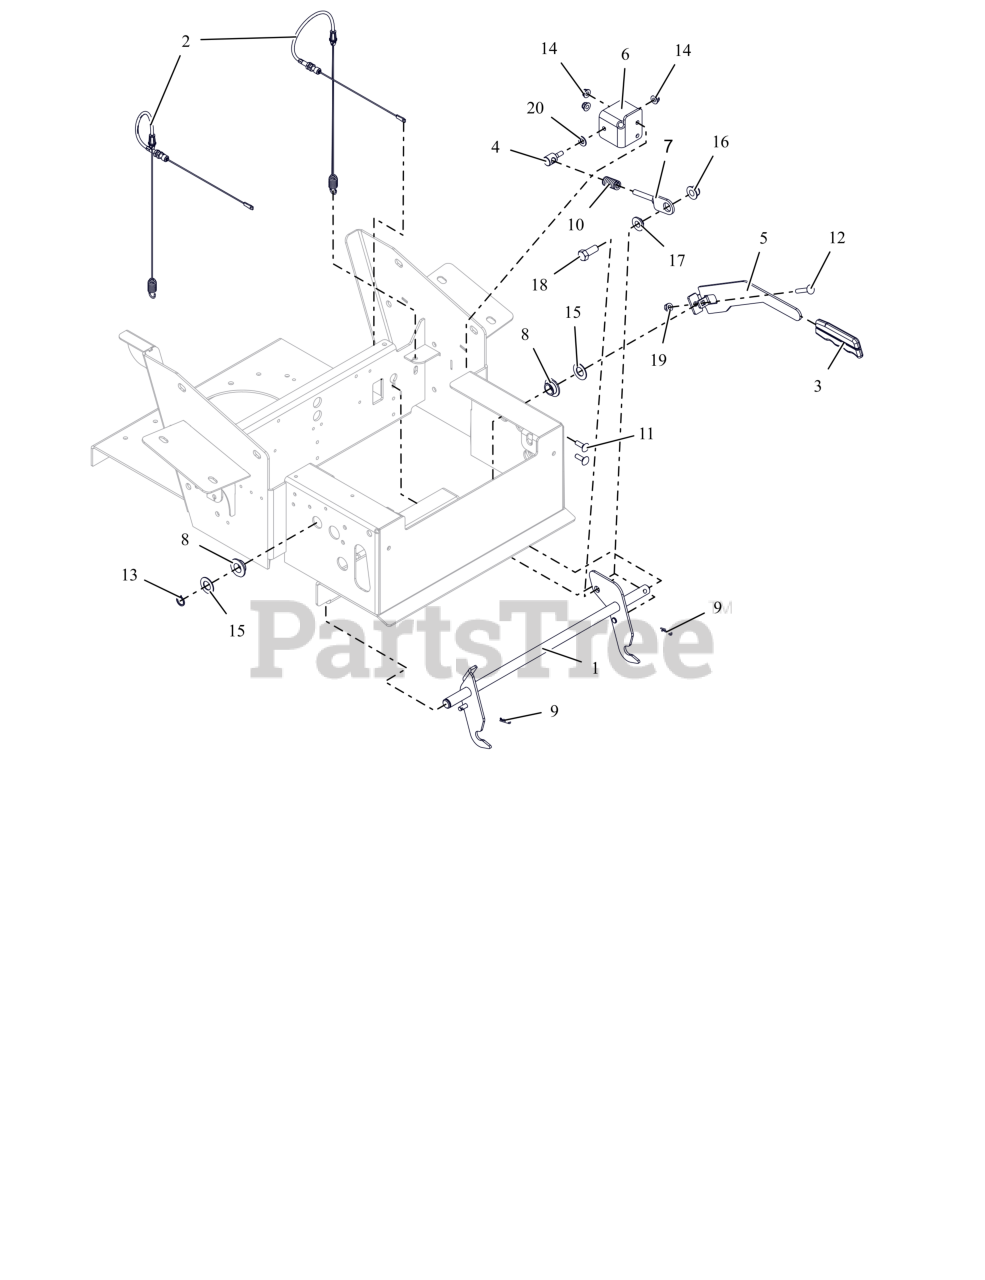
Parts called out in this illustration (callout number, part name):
1	WLDMT, PT/PT100 BRAKE LEVER
2	CABLE, BRAKE ACCUATING
3	GRIP, PARKING (GRAY)
4	TRUNNION, .38-16
5	PT/PT100 BRAKE HANDLE - BLK
6	TRUNNION MTG BRACKET - BLACK
7	WLDMT, BRAKE SPRING MOUNTING
8	BSHG, FLANGED .762 X 1.48 X .44 IGLIDER
9	PIN, HAIR #213 .08X1.19 ZCC
10	SG-COMP .142 X .710 X 1.75
11	BLT,RHSN .31-18X1.00 G5 ZCC
12	BLT, RHSN .31-18X1.75 G5 ZCC
13	RG-RTNG-EXT .689X.078
14	NUT,NYL-FLG .31-18 GF ZCC
15	WSHR, FLT .755X1.375X.062 ZCC
16	NUT,NYL-FLG .50-13 GF ZCC
17	BSHG-FLG .515X.750X.310X1.120
18	BLT,HEX .50-13X1.25 G5 ZCC
19	NUT,LK-CTR-FLG .31-18 GF ZCC
20	WSHR,FLT .406X.812X.065 ZCC
